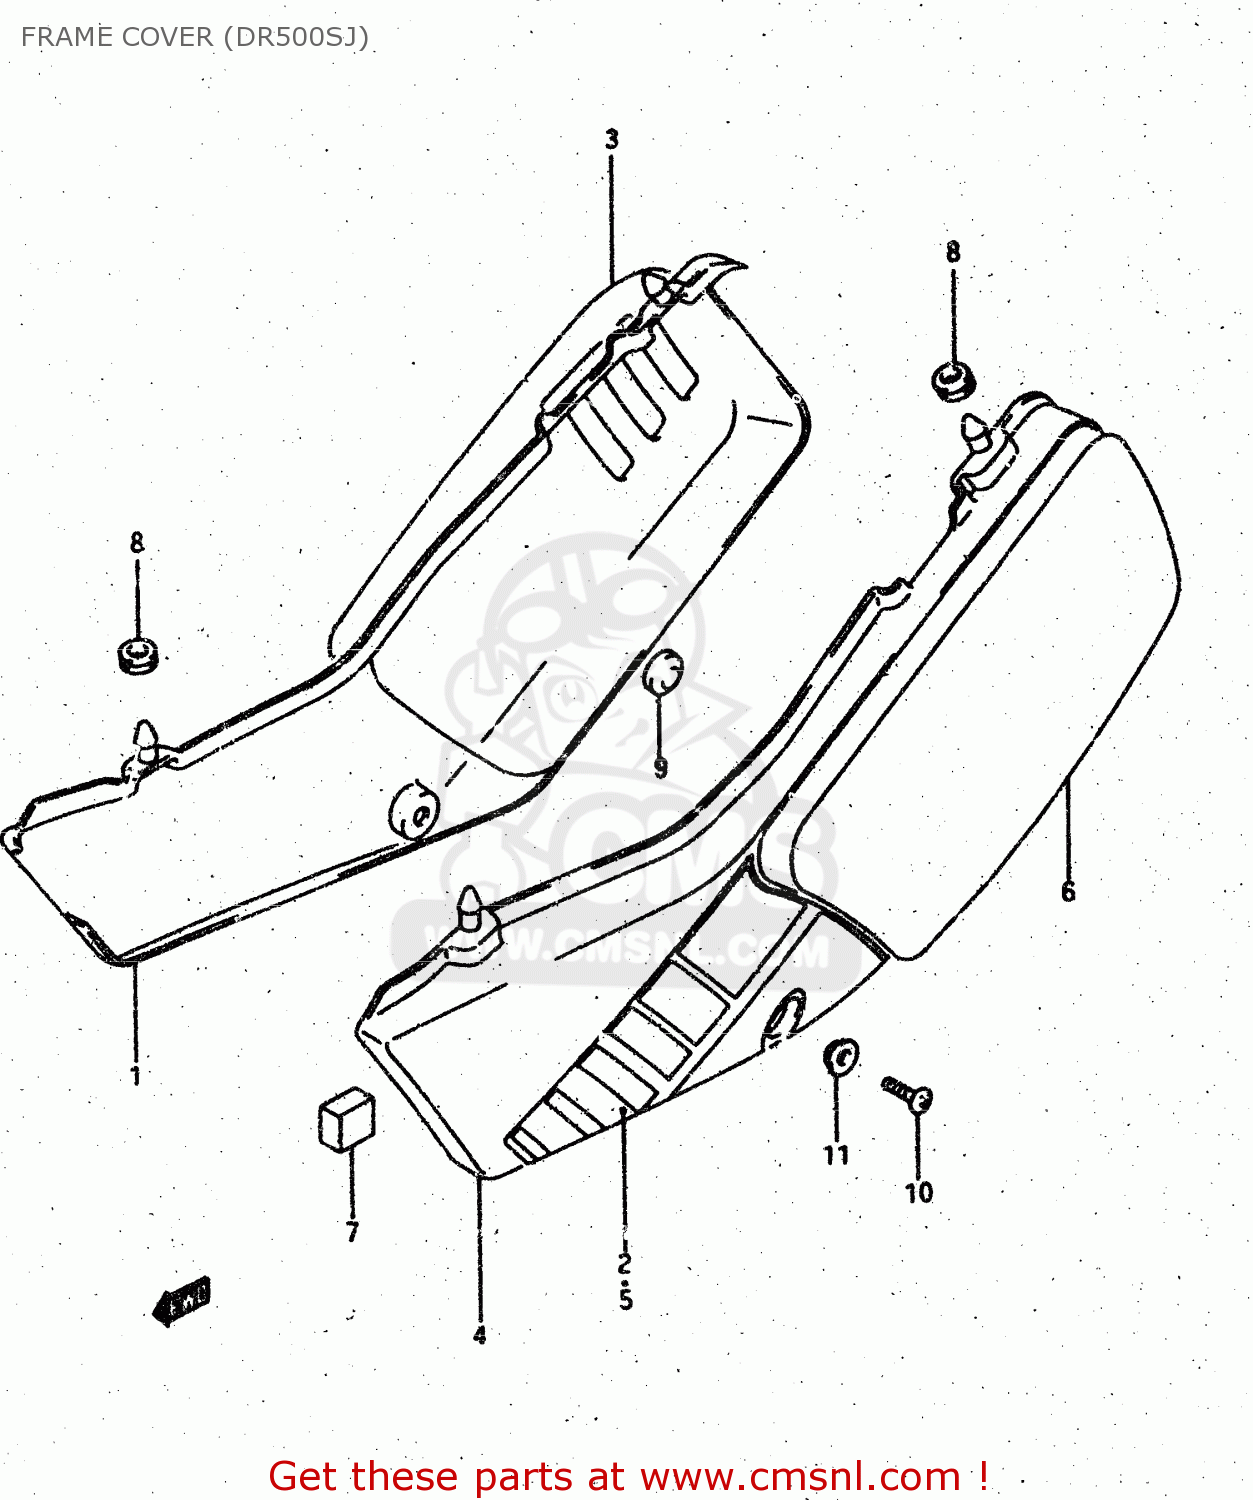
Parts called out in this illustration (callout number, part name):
1	COVER, SIDE RH (BLUE)
2	TAPE, FRONT RH
3	TAPE, REAR RH (BLUE)
4	COVER, SIDE LH (BLUE)
5	TAPE, FRONT LH
6	TAPE, REAR LH (BLUE)
7	CUSHION,FRAME COVER
8	CUSHION,SIDE COVER BOSS
9	CUSHION
10	SCREW 6X12
11	WASHER
